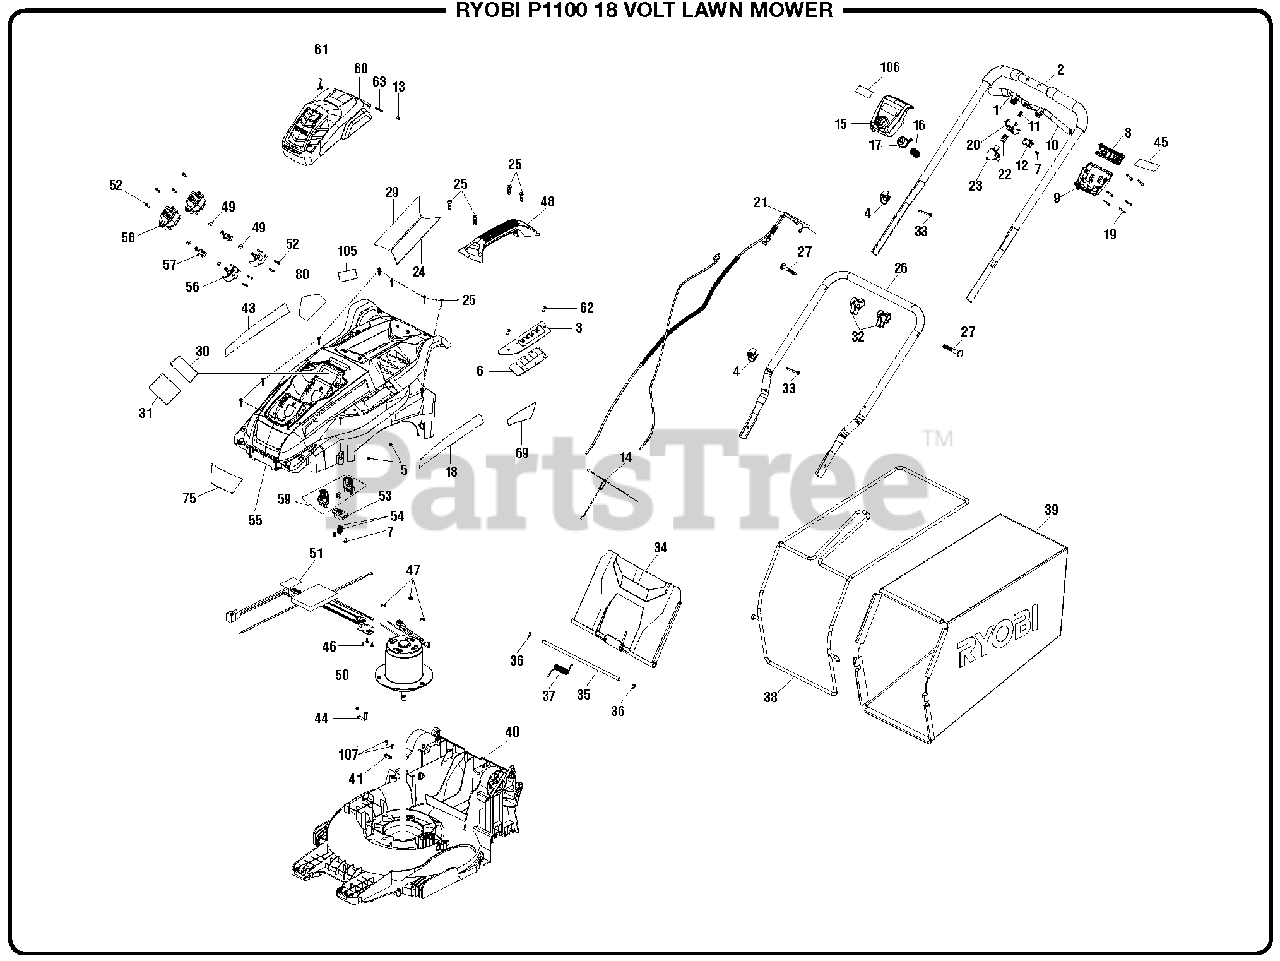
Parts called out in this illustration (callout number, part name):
1	Trigger Handle (Right Power Lever)
2	Upper Handle Assembly
3	Height Adjustment Plate
4	Cord Clamp
5	Lock Nut (M5)
6	Dust Gasket
7	Screw (M4 x 12 mm, T20 Torx Pan Hd.)
8	Lower Cover (Stain Handle)
9	Lower Cover (Trigger Housing)
10	Trigger Handle (Left Power Lever)
11	Compression Spring
12	Switch
13	Battery Door Axle
14	Lead Wire w/Terminal Block
15	Upper Cover (Control Assembly)
16	Button Return Spring
17	Start Button
18	Lithium Label (Left)
19	Screw (M4 x 30 mm, T15 Torx Pan Hd.)
20	Slider (Switch Box)
21	Starter Cable (Long)
22	Torsion Spring
23	Switch Holder
24	Warning Icon Label (Right)
25	Screw (M3.5 x 20 mm, T20 Torx Pan Hd.)
26	Lower Handle
27	Screw (M8 x 57 mm)
29	Warning Icon Label (Left)
30	Start Key Label (Eng)
31	Start Key Label (FR/SP)
33	Screw (M3 x 20 mm, Pan Hd.)
34	Rear Discharge Door
35	Rear Door Axle
36	Retaining Ring (E)
37	Torsion Spring (Rear Door)
38	Bag Frame
41	Cord Clip
43	Lithium Label (Right)
44	Mounting Bracket
45	Starting Instructions Label
46	Screw (M3 x 8 mm,Phillip Pan Hd.)
47	Lock Nut (M6)
49	Rubber Cushion
51	Soft Start Circuit Board
52	Screw (M4 x 16 mm, T20 Torx Socket Pan Hd.)
53	Key Holder
54	Female Terminal
55	Deck Cover
56	Press Cover (Battery Connect)
57	Plate (Battery Connect)
58	Base (Battery Connect)
59	Start Key
60	Battery Cover
61	Torsion Spring (Battery Door)
62	Screw (M5 x 0.8 mm, Pan Hd.)
63	Pressure Spring
69	Cut Diameter Label (Left)
75	Ryobi Logo Label (Front)
80	Cut Finger Label
105	Data Label
106	Ryobi Logo label (Handle)
107	Screw (M4 x 16 mm, T20 Torx Pan Hd.)
